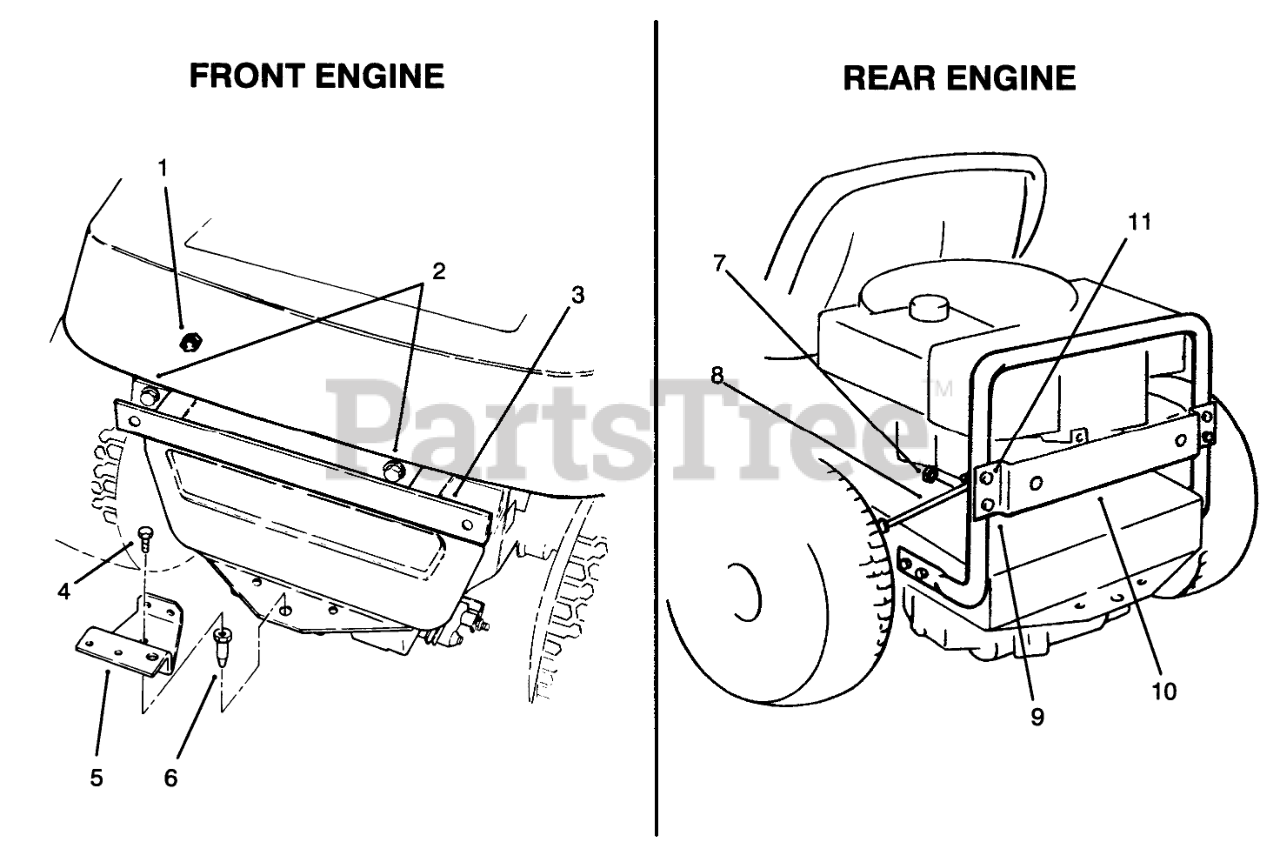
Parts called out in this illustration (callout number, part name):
1	NUT-LOCK, NI
2	SCREW-HH
3	Bracket-Channel
4	SCREW-HH
5	Bracket-Bagger Mounting
6	PIN-MOUNTING, LOWER
7	NUT-LOCK, NI
8	BAGGING KIT BRACE
9	SCREW-HH
10	Plate-Bagging Kit
11	SCREW-HH
